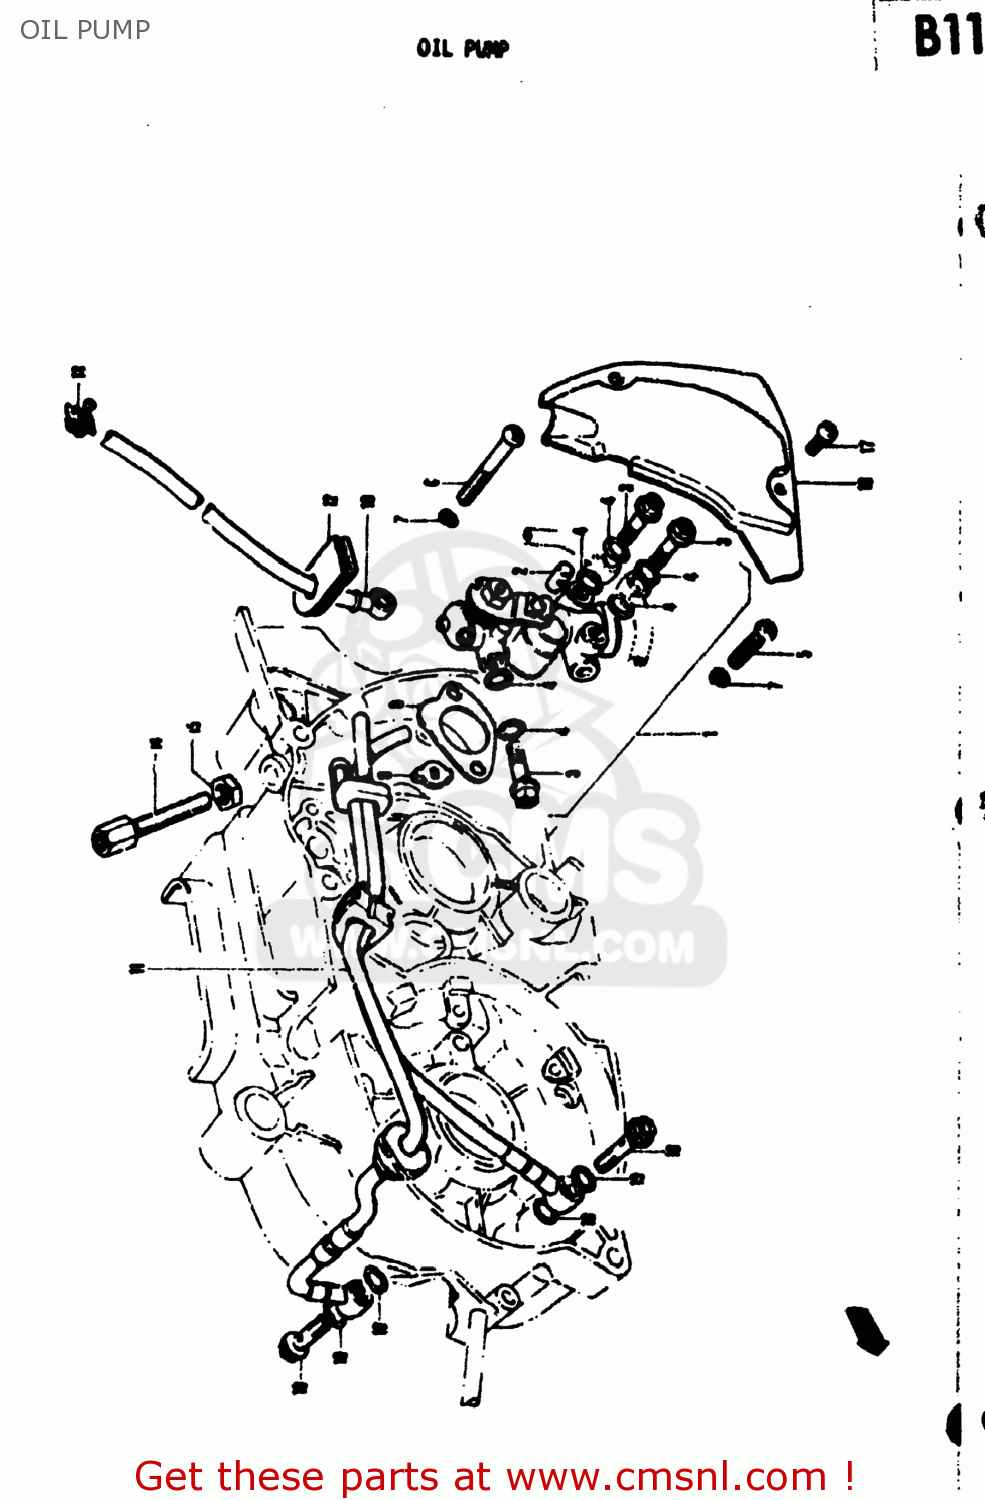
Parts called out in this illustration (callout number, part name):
1	COOLER SET,OIL
2	TERMINAL,CABLE
3	Union Bolt
4	GASKET (NAS)
5	SCREW
6	SCREW
7	LOCK WASHER
8	GASKET,OIL PUMP (MCA)
9	PIECE,OIL PUMP DRIVE
10	HOSE,OIL NO.1
11	HOSE,OIL NO.2
12	GROMMET
13	CLAMP
14	BOLT
15	NUT
16	CAP,OIL PUMP INSPECTION
17	SCREW
18	UNION BOLT
19	GASKET (NAS)
